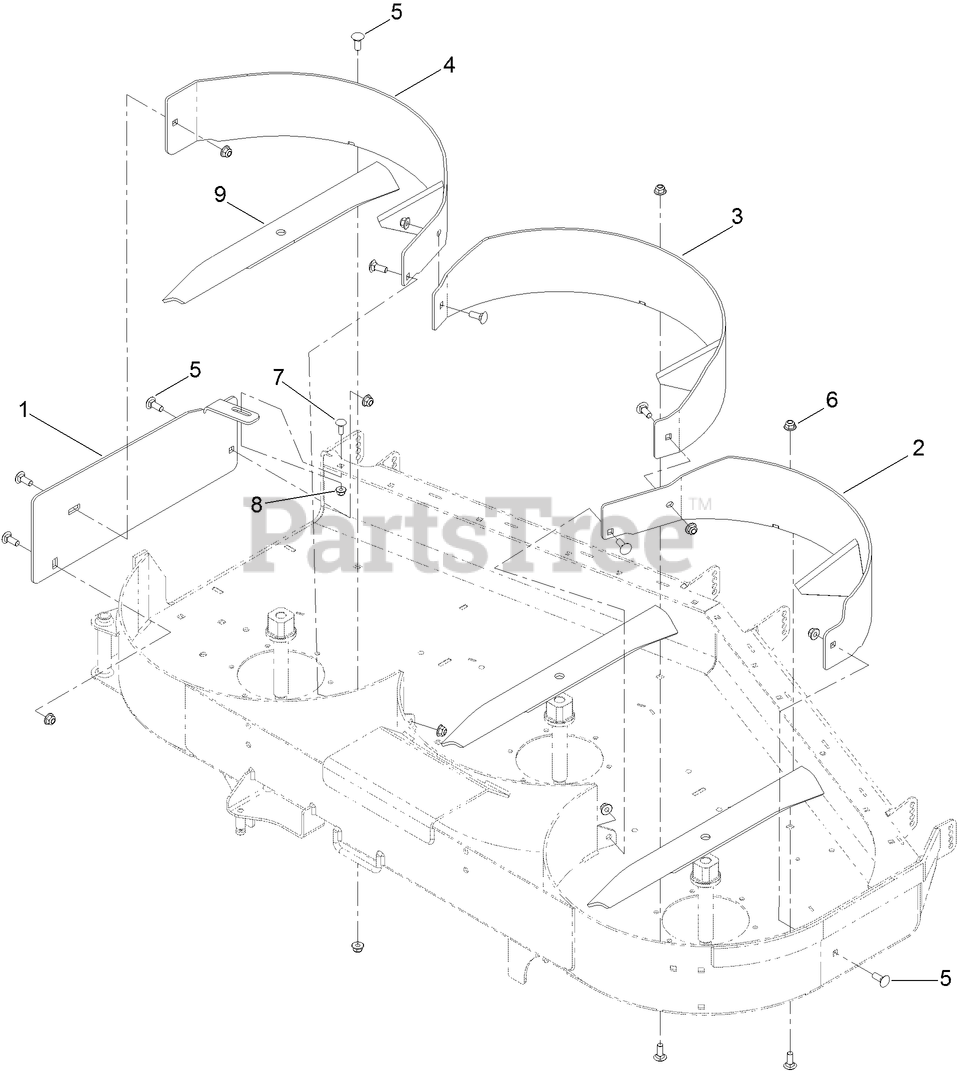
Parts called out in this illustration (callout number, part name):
1	PLATE-COVER, DISCHARGE
2	BAFFLE-LH
3	BAFFLE-CENTER
4	BAFFLE-RH
5	BOLT-CARR
6	NUT-HF, NI
7	SCREW-CARR
8	NUT-HF, NI
9	BLADE-ROTARY, RECYCLING 20.5IN
